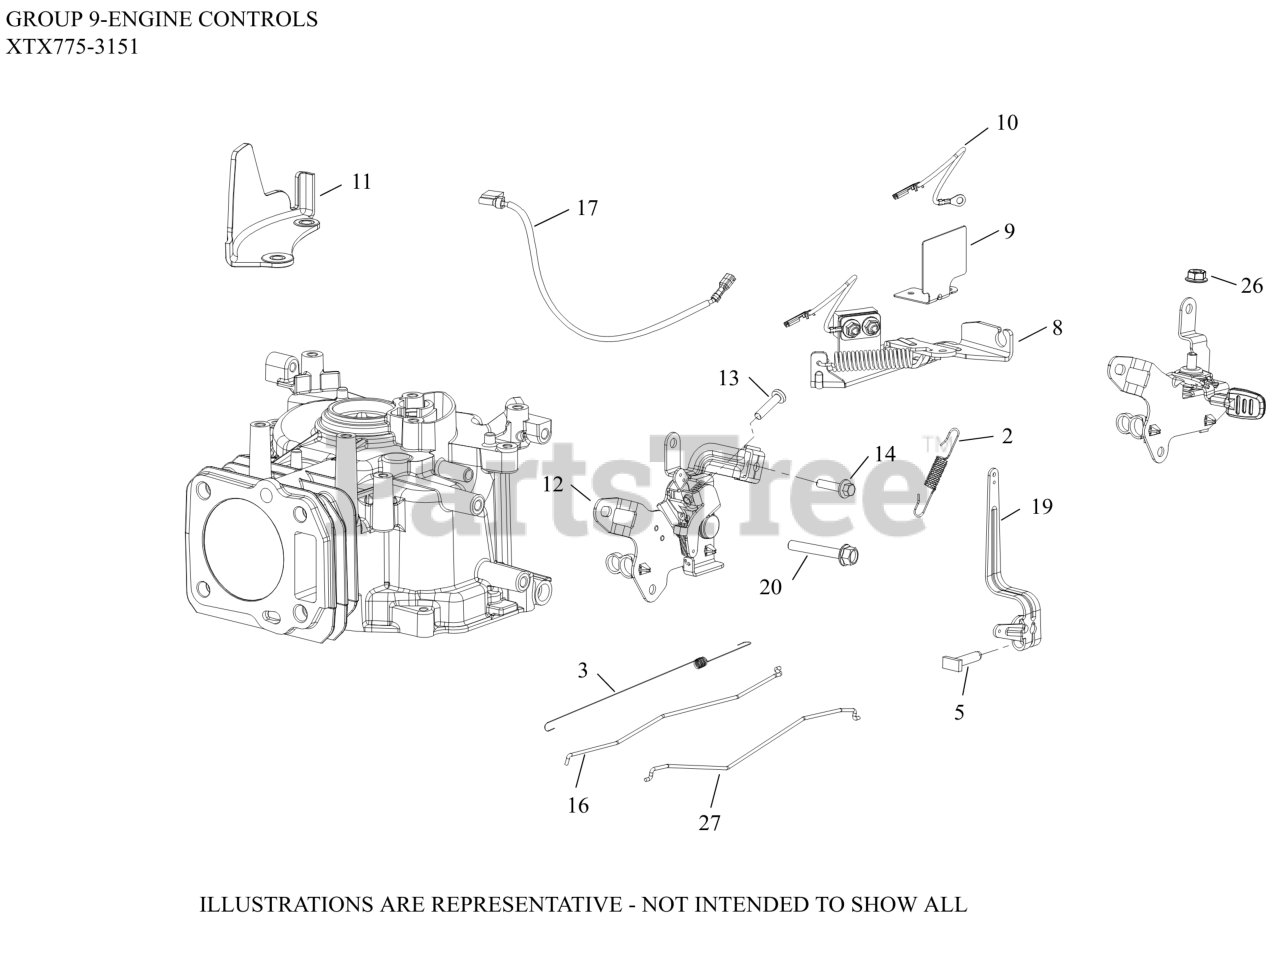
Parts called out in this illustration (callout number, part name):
2	SPRING, EXTENSION (GOVERNOR)
3	SPRING, LINKAGE
5	SCREW, RECTANGLE HEAD (M6)
8	BRAKE ASSEMBLY
9	GUARD, BRAKE - USE 14 314 30-S
10	LEAD, KILL (BRAKE TO IGN. MODULE)
11	GUARD, FINGER
12	CONTROL ASSEMBLY (VAR. SPEED)
13	SCREW, #25 6-LOBE PAN HD (M5)
14	SCREW, (M5) HEX FLANGE
16	LINKAGE, GOVERNOR
19	LEVER, GOVERNOR
20	SCREW, HEX FLANGE (M6)
26	NUT, HEX FLANGE LOCK (M6)
27	LINKAGE, CHOKE
